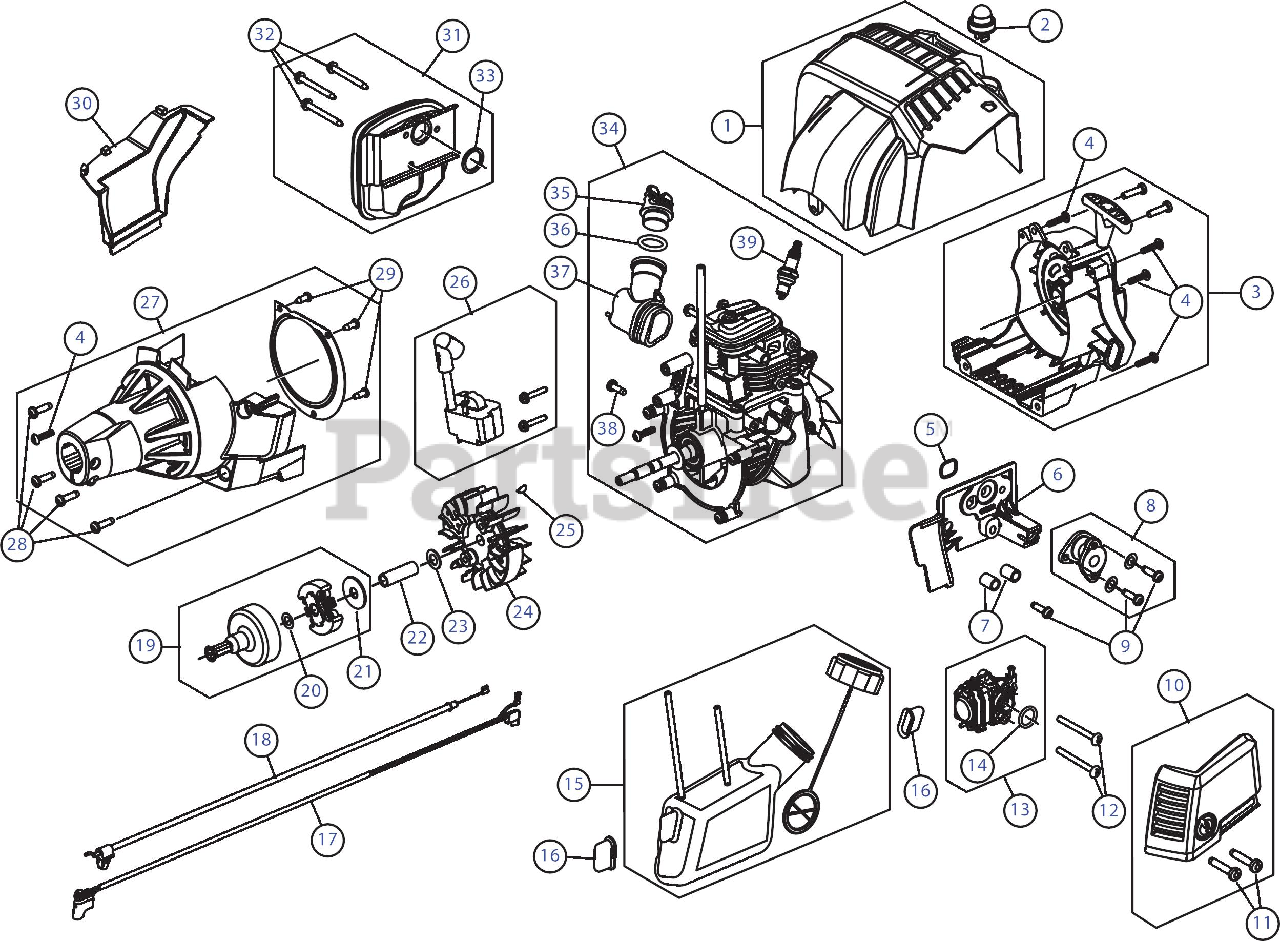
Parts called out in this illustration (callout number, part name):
1	Top Housing
2	Air Purge Primer
3	Starter Housing Assembly (includes 4)
5	O-Ring
6	Intake Port
7	Air Cleaner Spacer
8	Boot Assembly (includes 9)
9	Screw
10	Air Cleaner Assembly
10	Air Filter
13	Carburetor Assembly (includes 14)
15	Fuel Tank Assembly
16	Fuel Tank Pad
17	Lead Wire
18	Throttle Cable
19	Clutch Assembly (includes 20 & 21)
20	Thrust Washer
21	Clutch Washer
22	Spacer
23	Washer
24	Flywheel
26	Module Assembly
27	Clutch Cover Assembly (includes 4, 28 & 29)
29	Screw
30	Rear Engine Cover
31	Muffler Assembly (includes 32 & 33)
33	Muffler Gasket
34	Shortblock Assembly (includes 35 - 39)
35	Oil Fill Plug
36	O-Ring
37	Oil Fill Tube
38	Screw
39	Spark Plug
